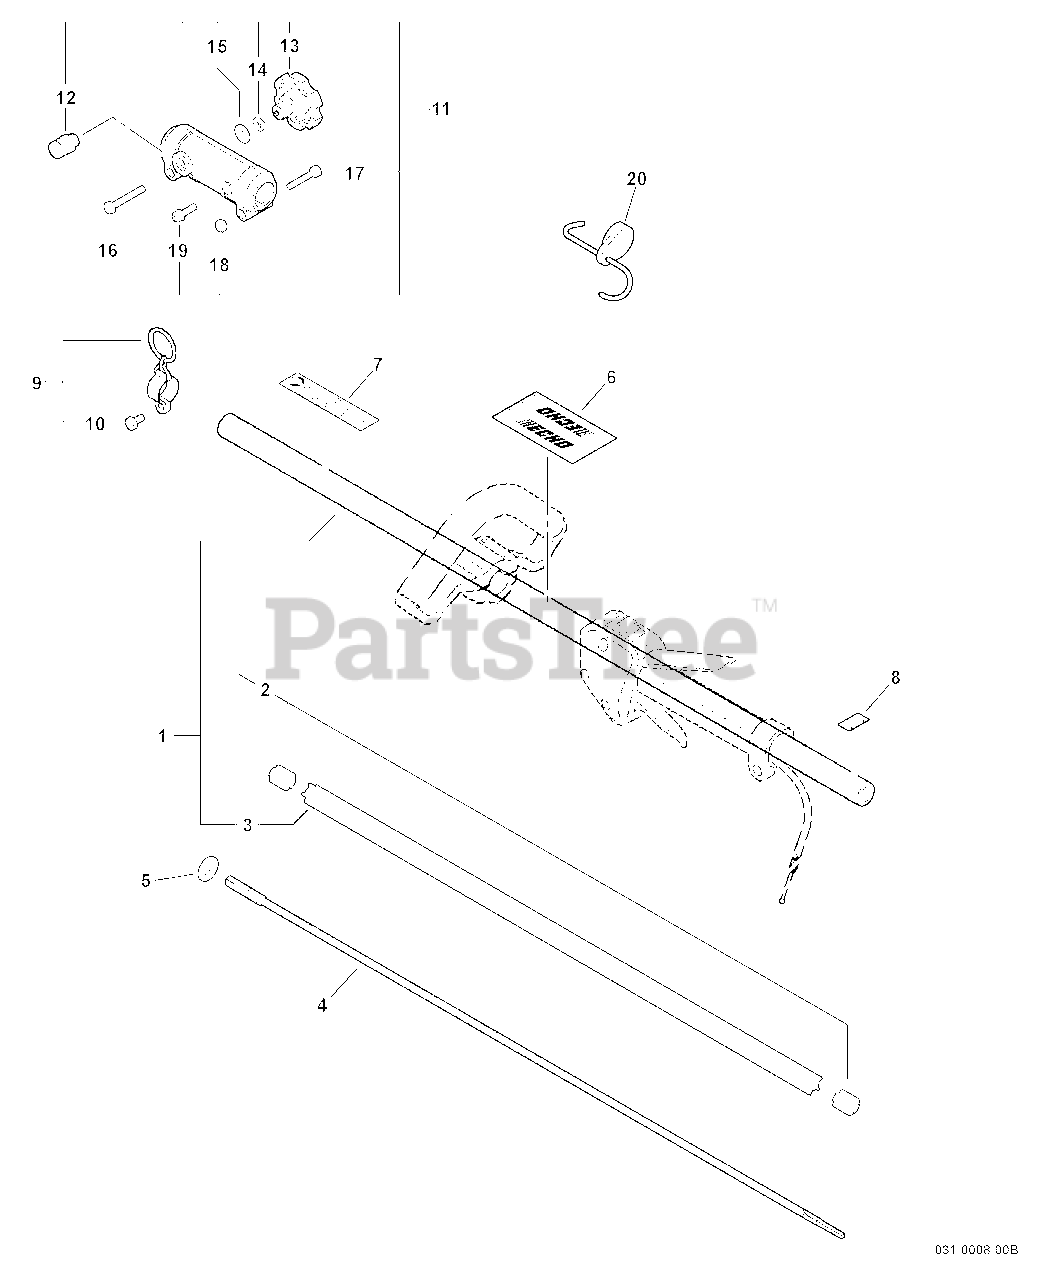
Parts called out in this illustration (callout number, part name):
1	MAIN PIPE ASSY
3	LINER - FLEXIBLE
4	DRIVESHAFT - FLEXIBLE -- UPPER
6	LABEL - HANDLE LOCATION
7	LABEL - CAUTION -- SPANISH
8	LABEL - ALIGNMENT
9	HANGER KIT
10	BOLT - 5X12
11	COUPLER ASSY
12	LATCH ASSY
13	THUMBSCREW
14	LOCKWASHER - 5
15	WASHER - 5
16	BOLT - 5X35
17	SCREW - 5X30
19	SCREW - 5X14
20	PAS ATTACHMENT HANGER
